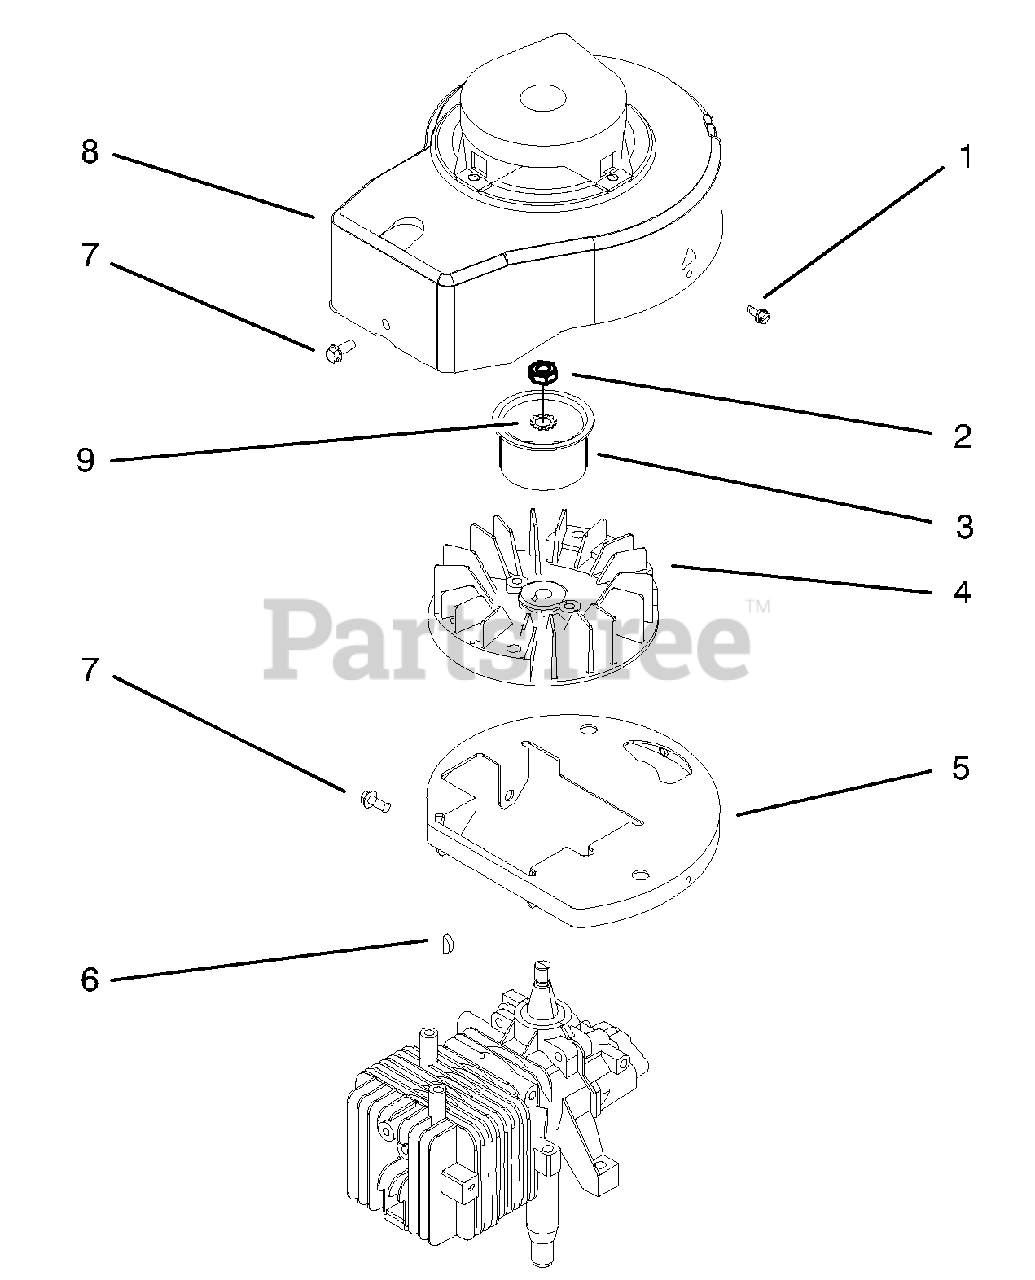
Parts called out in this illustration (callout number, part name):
3	Hub-Starter
4	Flywheel
5	Base-Shroud
7	Screw
8	Shroud Assembly
9	Washer-Lock
